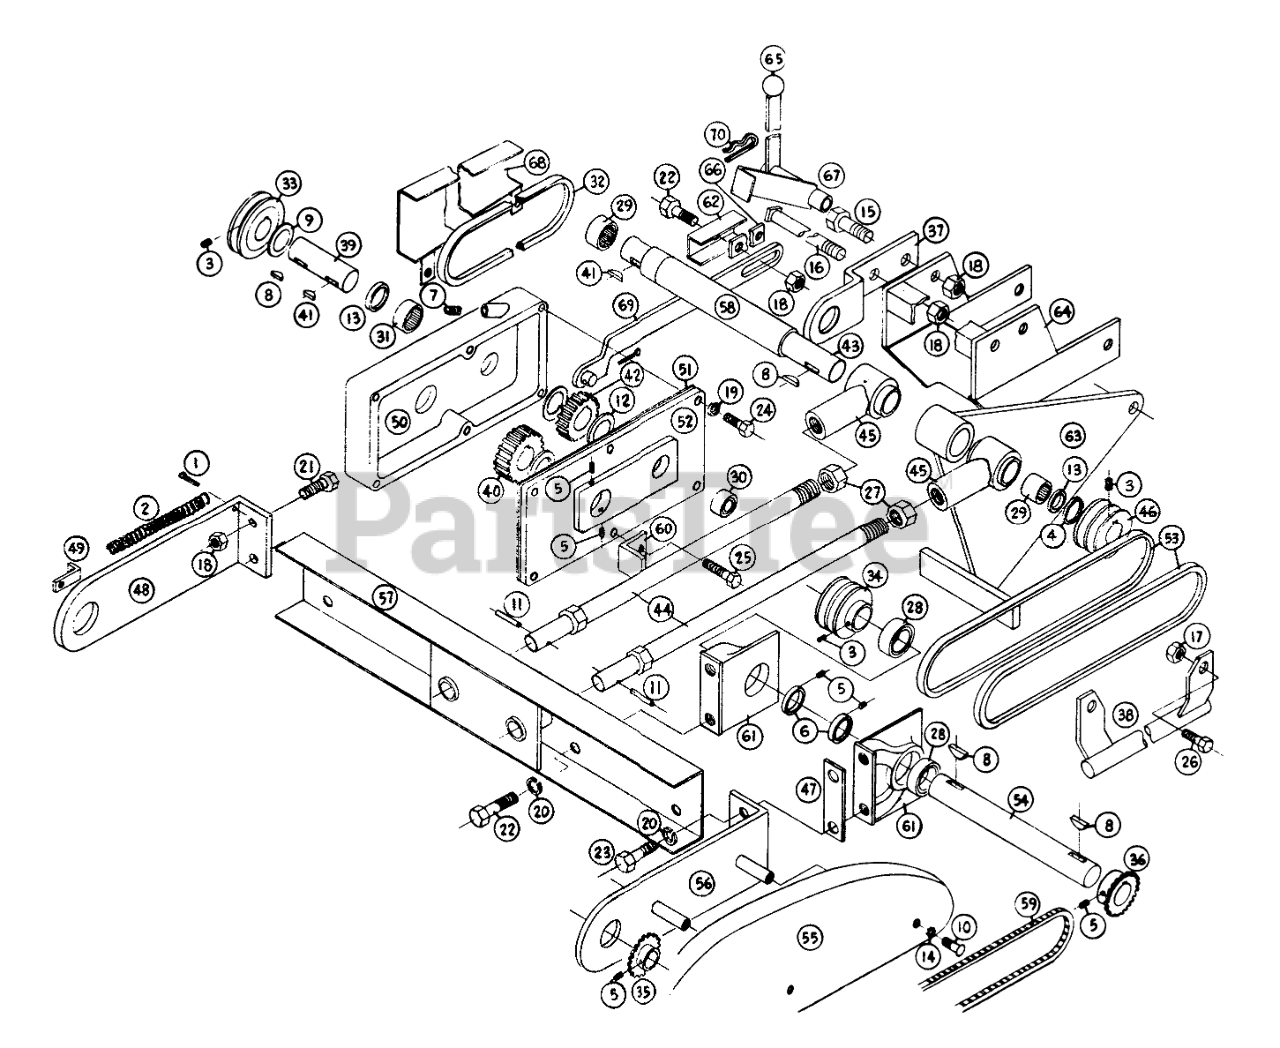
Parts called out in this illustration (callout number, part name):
1	Cotter Key
2	Spring
3	Snap Ring
4	Flat Washer
5	Set Screw 1/4-20 x 1
6	Collar
7	Pipe Plug
8	Key-#9
9	Flat Washer
10	Rd. Hd. Slotted Machine #8-32
11	Roll Pin
12	WASHER
13	Seal
14	Shakeproof Washer 8132
15	Bolt Hex. 3/8-16 x 7/8
16	Sq. Hd. Machine Bolt 3/8-16 x 8
17	1/4-20 Lock Nut
18	Nut
19	Lockwasher 1/4
20	Lockwasher 3/8
21	Bolts 3/8-16 x 3/4
22	Bolt 3/8-16 x 1
23	Collar w/Setscrew
24	1/4-20 x 5/8 Hex Hd. Cap Screw
25	1/4-20 x 3/4 H.H.C.S.
26	Bolt 1/4-20 x 1 CP
27	Hex Jam Nut 3/4
28	Ball
29	BEARING-NEEDLE
30	BEARING-NEEDLE
31	NEEDLE BEARING
32	V Belt A section 76"
33	PULLEY
34	PULLEY
35	Clevis
36	Sprocket
37	Front Mounting Bracket
38	Lift Rod
39	Drive Shaft
40	Jack Shaft Gear
41	Woodruff Key #9
42	Drive Gear
43	Lower Drive Shaft
44	Hanger Rod W/A
45	End Hanger Rod
46	Pulley
47	Shim
48	End Channel Support R.H.
49	CLIP - SPRING
50	Gear Box
51	Gasket
52	Cover
53	V Belt 3-"W 34"
54	Mower Shaft
55	Chain Guard
56	End Channel Support L.H.
57	Mounting Channel
58	Pivot Tube
59	Chain 70 links
60	Stop Bracket
61	Bearing Support
62	Brace Clutch Bar
63	Lift Ass-y.
64	Mounting Bracket (Special)
65	Knob
66	Link
67	Clutch Assembly
68	Belt Guard
69	Knob
70	Hair Pin
